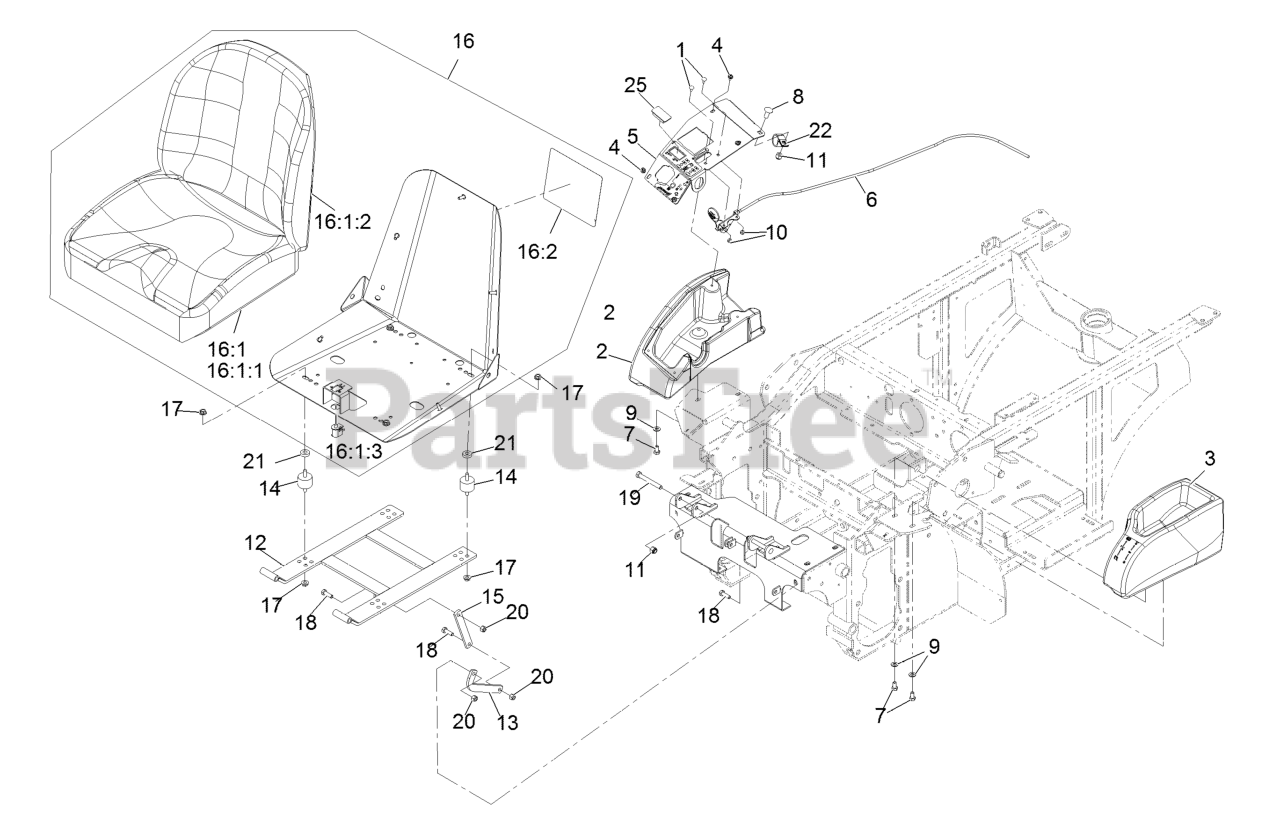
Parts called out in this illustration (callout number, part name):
1	BOLT-CARR
2	CONSOLE-RH
4	SCREW-PPH
5	CONTROL PANEL ASM
6	CABLE-THROTTLE
7	SCREW-HH
8	SCREW-CARR
9	WASHER-PLAIN
10	NUT-LOCK, NI
11	NUT-LOCK, NI
12	FRAME-SEAT
13	LINK-SEAT STOP
14	MOUNT-VIBRATION, RUBBER
15	LINK-SEAT
16:1	Asm-Seat
16:1:1	ASM-SEAT BOTTOM CUSHION
16:1:2	CUSHION,SEAT BACK
16:1:3	SWITCH-BAIL
16:2	DECAL-SERVICE AID
18	SCREW-HH
19	SCREW-CARR
20	NUT-LOCK, NI
21	SPACER
22	CLIP-LOOM
25	PLUG-HOLE
